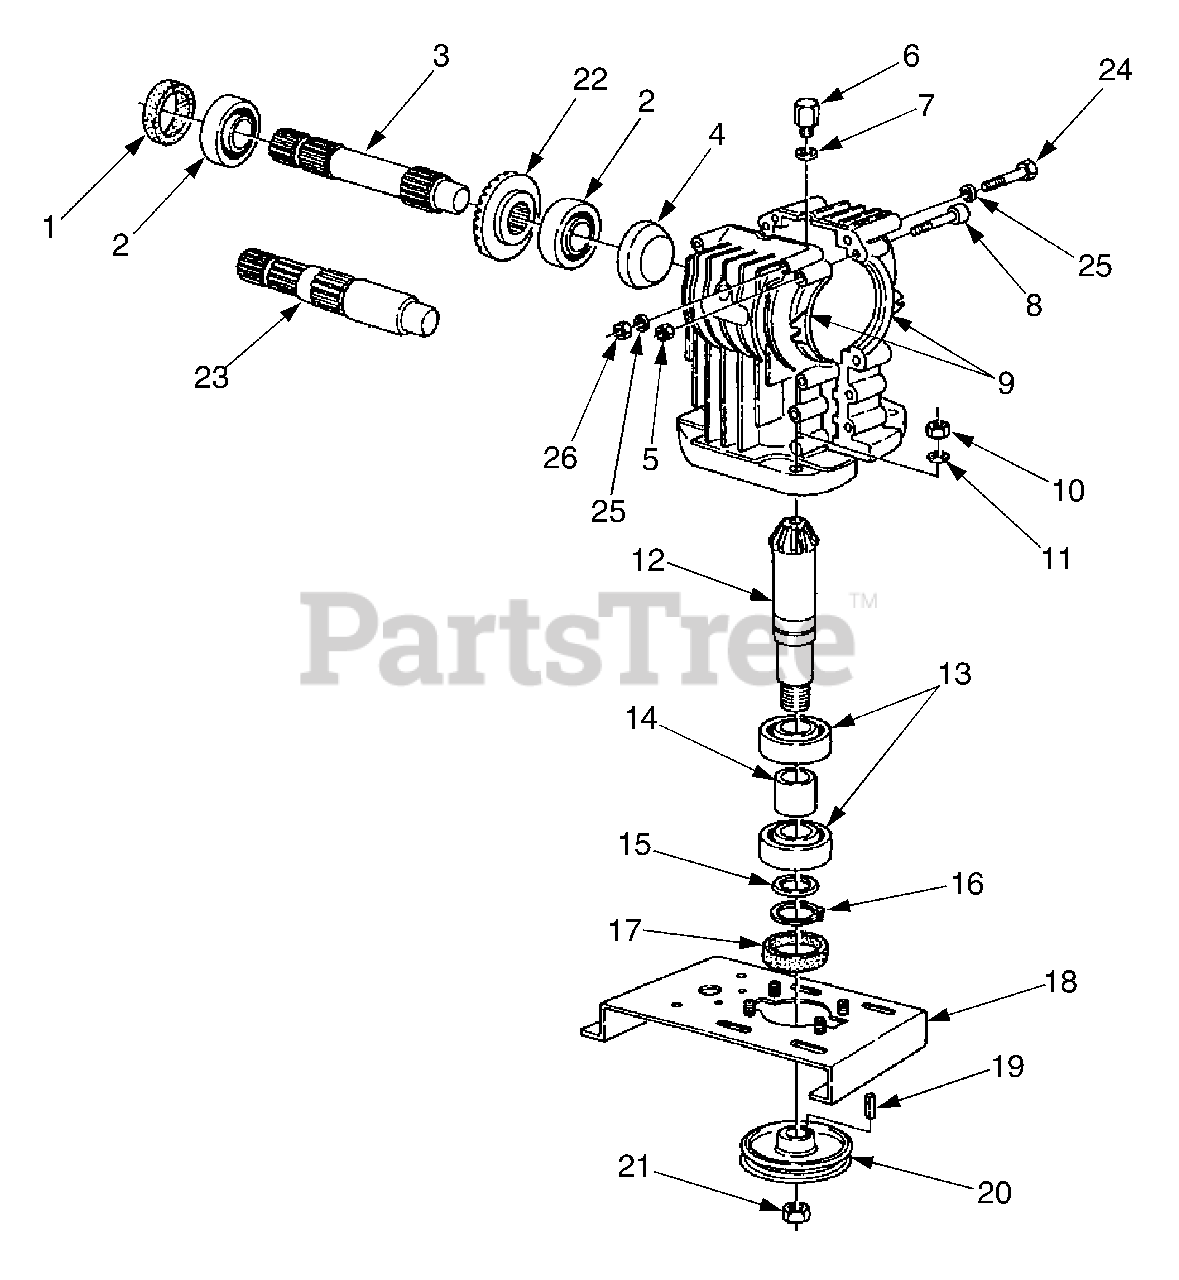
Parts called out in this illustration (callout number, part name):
3	Input Shaft
6	Breather Cap
8	Bolt, 8 x 50
9	Gearbox Housing w/Hole
10	Nut, M12
11	Lock Washer, M12
12	Pinion Gear
15	Spacer Washer
18	Center Plate
19	Key, 7 x 8 x 35
23	Input Shaft
24	Bolt, 10 x 120
25	Flat Washer, M10
